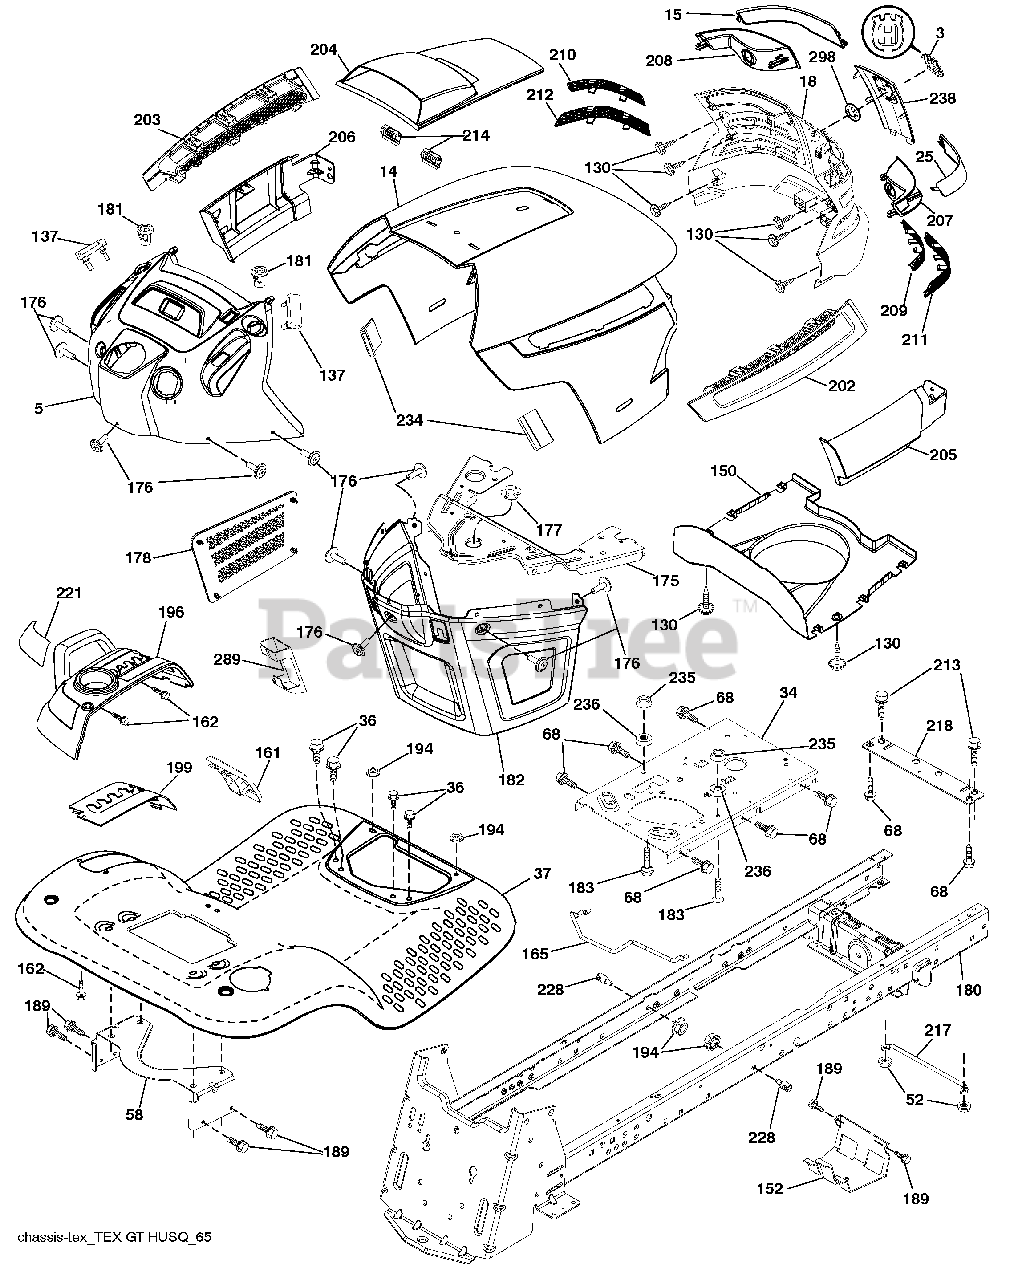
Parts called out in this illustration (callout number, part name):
3	Logo
5	Dash
14	Hood Asm.
18	Grille Asm.
34	Plate Engine
36	Screw 5/16-18 x 3/4
37	Fender
52	Nut Crown Lock 5/16-18
58	Bracket Fender
68	Screw 5/16-18 x 1/2
130	Screw #10 x .750 BOS Thread
137	Bumper Dash
150	Duct Heat Hood
152	Shield Browning/Debris
161	Console Fuel Window
162	Screw Hex Wsh Hi-Lo 1/4 x 1/2
165	Bracket Support Tank
175	Crossmember
176	Screw 10-24 x 5/8
177	Bushing Steering
178	Cargo Asm. Net
180	Chassis
181	Bushing Mtg. Fender Crgo.
182	Dash Lower
183	Bolt Fin Hex 5/16-18 unc x 1-1/4
189	Screw 5/16-18 x 3/4
194	Nut Lock Hex Flange 5/16-18
196	Console Asm. Deck Lift
199	Plate Deck Lift
202	Vent Side Hood RH
203	Vent Side Hood LH
204	Vent Asm Hood Top
205	Skirt Hood Side RH
206	Skirt Hood Side LH
209	Insert Hex Top RH
210	Insert Hex Top LH
211	Insert Hex Bottom RH
212	Insert Hex Bottom LH
213	Bolt Hex Hd 5/16-18 unc x 3/4
214	Clip Retainer
221	Reflector LH
228	Stud Fastener
234	Bumper Hood
235	Spacer Fender
236	Nut Center Lock 5/16-18 unc
289	Plug Cruise/Phone
